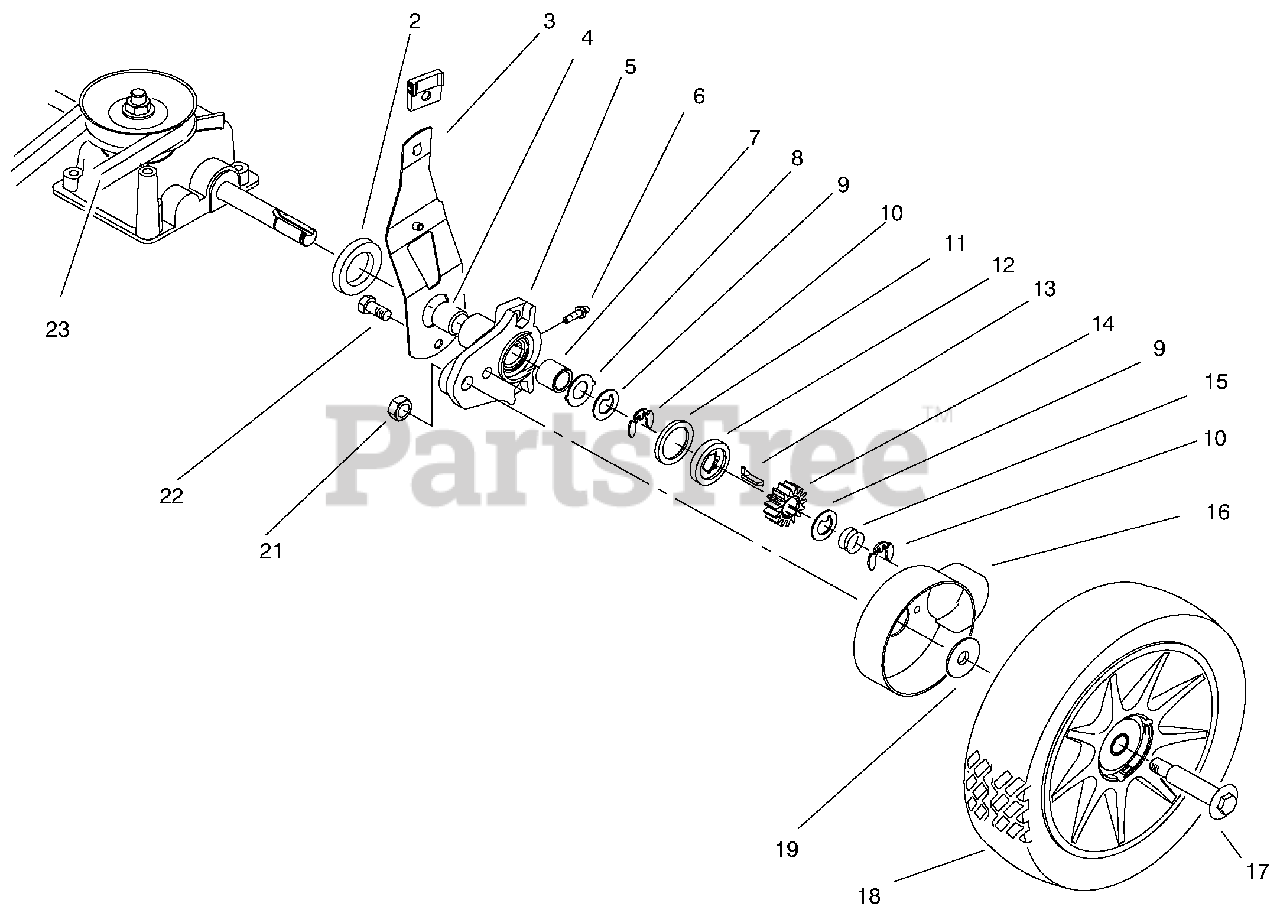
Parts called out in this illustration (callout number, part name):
2	Spacer-Axle Shaft
3	Spring Arm Ass'y
5	Pivot Arm Ass'y-Rear (Incl. Ref.#4, 6, & 7)
6	Fitting-Grease
8	Washer-Thrust Pivot Arm
9	Washer-Thrust, Keyed
10	Ring-Klip. Special
11	Ring-Friction
12	Washer-Clutch, Plastic
13	Key-Rocking, LH
14	Gear-Pinion
15	Spring-Compression
16	Cover Wheel
17	Bolt-Wheel
18	Wheel Ass'y-8"
19	Washer-Stepped
